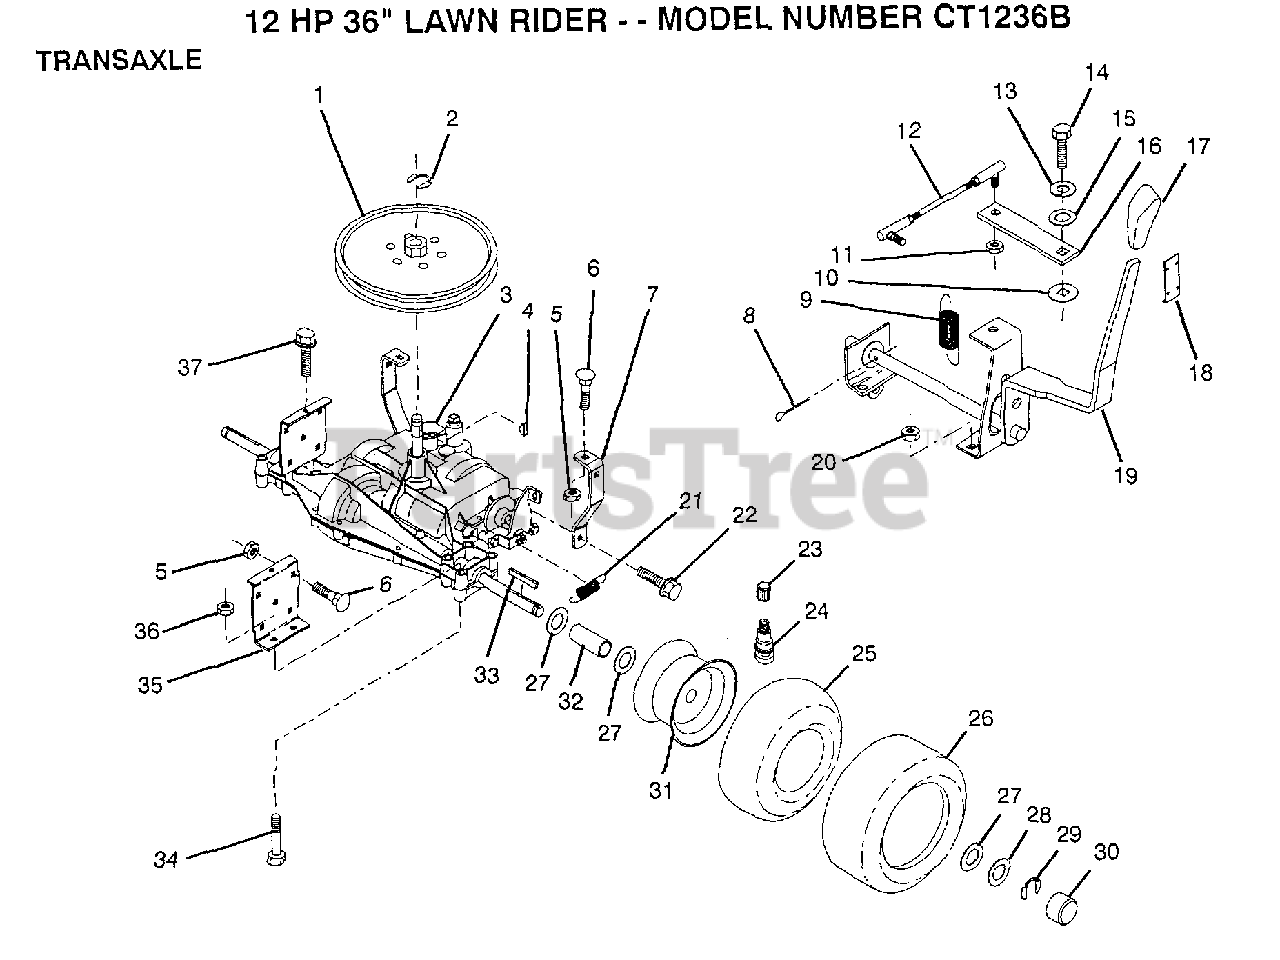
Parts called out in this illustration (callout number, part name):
1	PULLEY
6	BOLT
7	"STRAP,TORQUE"
8	PIN COTTER 1/8
9	"SPRING,EXT"
10	WASH-SHFT PLT LT
11	NUT.LOCK.5/16-24
12	"LINK,SHIFT"
13	LOCKWASHER
15	WASHER LT
16	"ARM,SHIFT"
17	"KNOB,SHT CONTROL"
18	KNOB RETAINER
22	SCREW LT
23	VALVE CAP
24	VALVE STEM LT
25	TUBE.16X6.5/7.5-8
27	WASHER
28	WASHER
29	E-RING LT
30	HUB CAP
32	SPACER
33	SQUARE KEY
34	BOLT
35	"BRKT,TRANSAXLE"
37	SCREW
